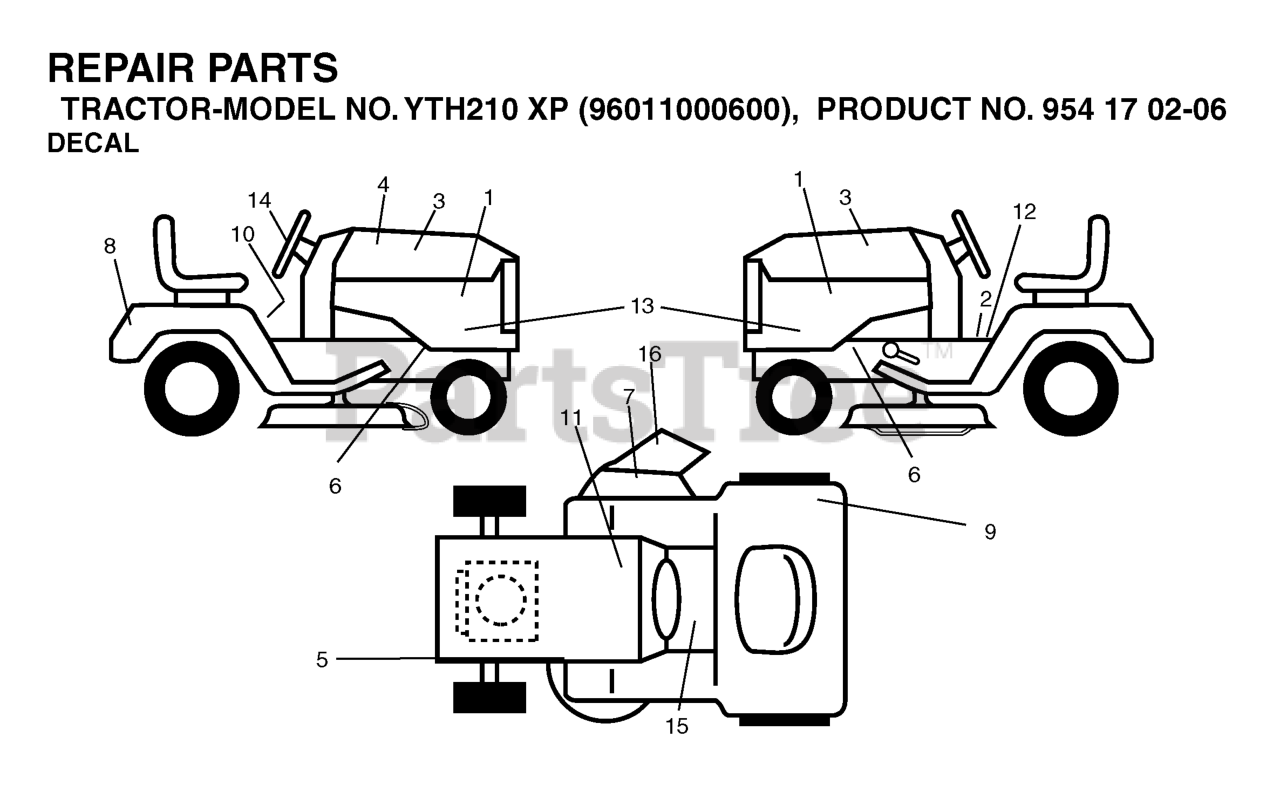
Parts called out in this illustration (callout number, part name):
1	DECAL.HOOD.HUSQVARNA.INTERNATI
2	DECAL PARK BRAKE
5	DECAL V BELT SCHEMATIC
7	DECAL.INTERNATIONL.CUTFINGER
9	Decal, Fender 100 DB/CE
10	DECAL READ OWNER'S MAN SYMS
11	DECAL BTRY SYMBOLS
12	DECAL
14	DECAL.STEERING.HUSQ.BLUE
15	DECAL
16	DECAL DECK "B" 42"
